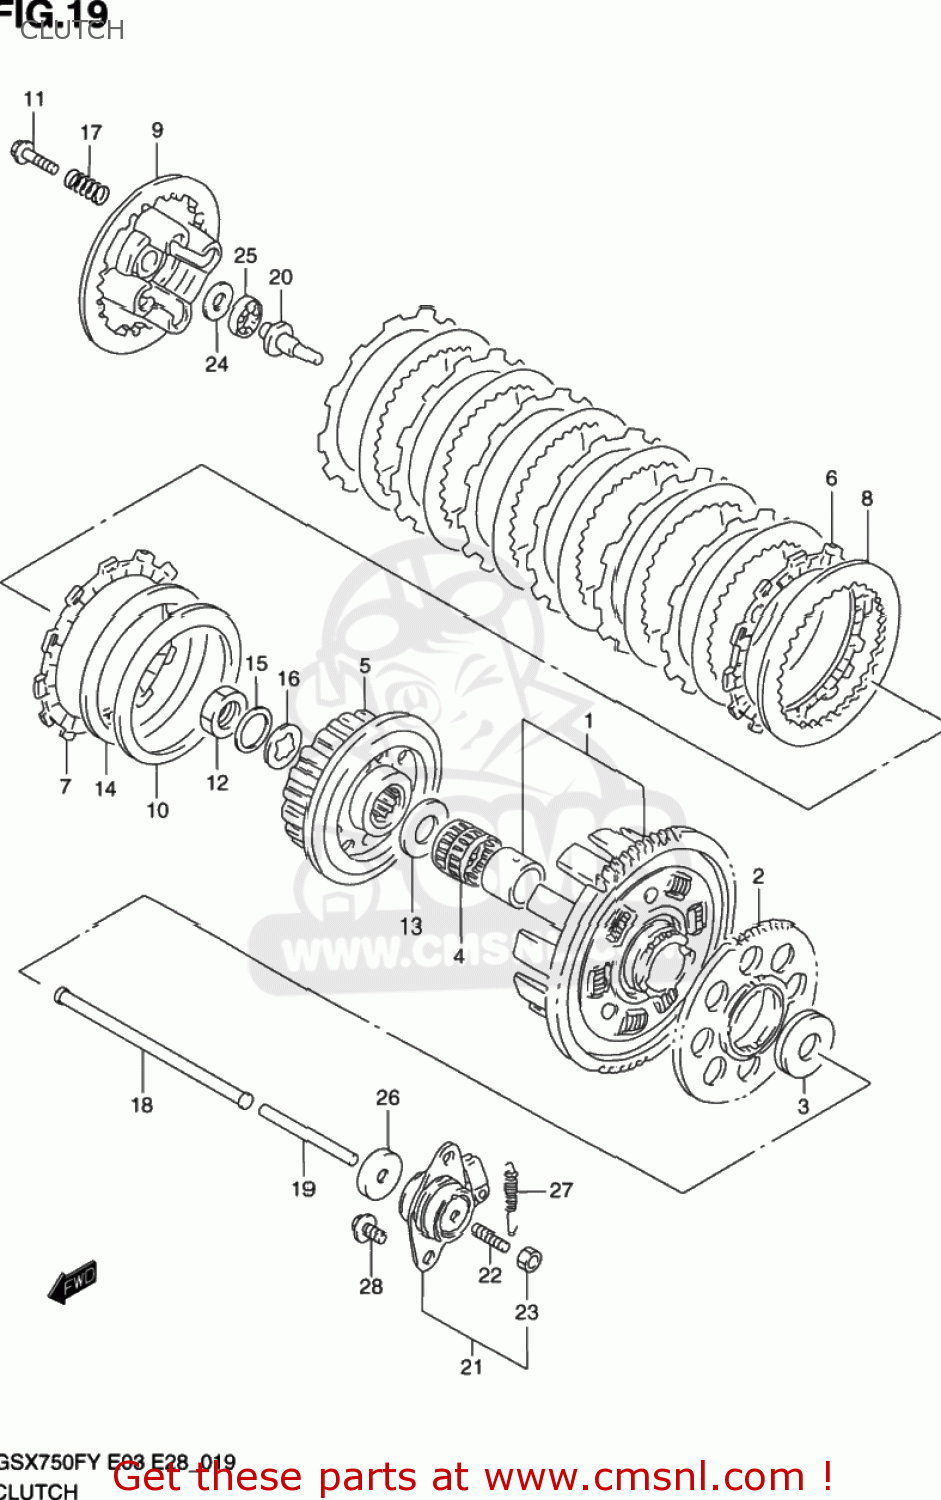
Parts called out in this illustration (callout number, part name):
1	GEAR ASSEMBLY,PRIMARY DRIVE
2	GEAR,GENERATOR DRIVE
3	WASHER(25X54X2.5)
4	BEARING(35X40X35.8)
5	HUB,CLUTCH SLEEVE
6	PLATE,CLUTCH DRIVE (NAS)
7	PLATE,CLUTCH DRIVE(T:3.5) (NAS)
8	PLATE,CLUTCH DRIVEN (NAS)
9	DISC,CLUTCH PRESSURE
10	SEAT,WAVE WASHER(T:1.4)
11	BOLT(6X20)
12	NUT
13	WASHER(25X50X2.5)
14	WASHER
15	WASHER
16	SHIM(22X36X1)
17	SPRING
18	ROD,CLUTCH PUSH,R
19	ROD,CLUTCH PUSH,L
20	PIECE,CLUTCH PUSH
21	SCREW ASSY,CLUTCH RELEASE
22	SCREW(6X25)
23	NUT
24	WASHER(15.5X28X1)
25	BEARING(15X28X2)
26	SEAL,OIL(6X34X5.5)
27	SPRING
28	BOLT
